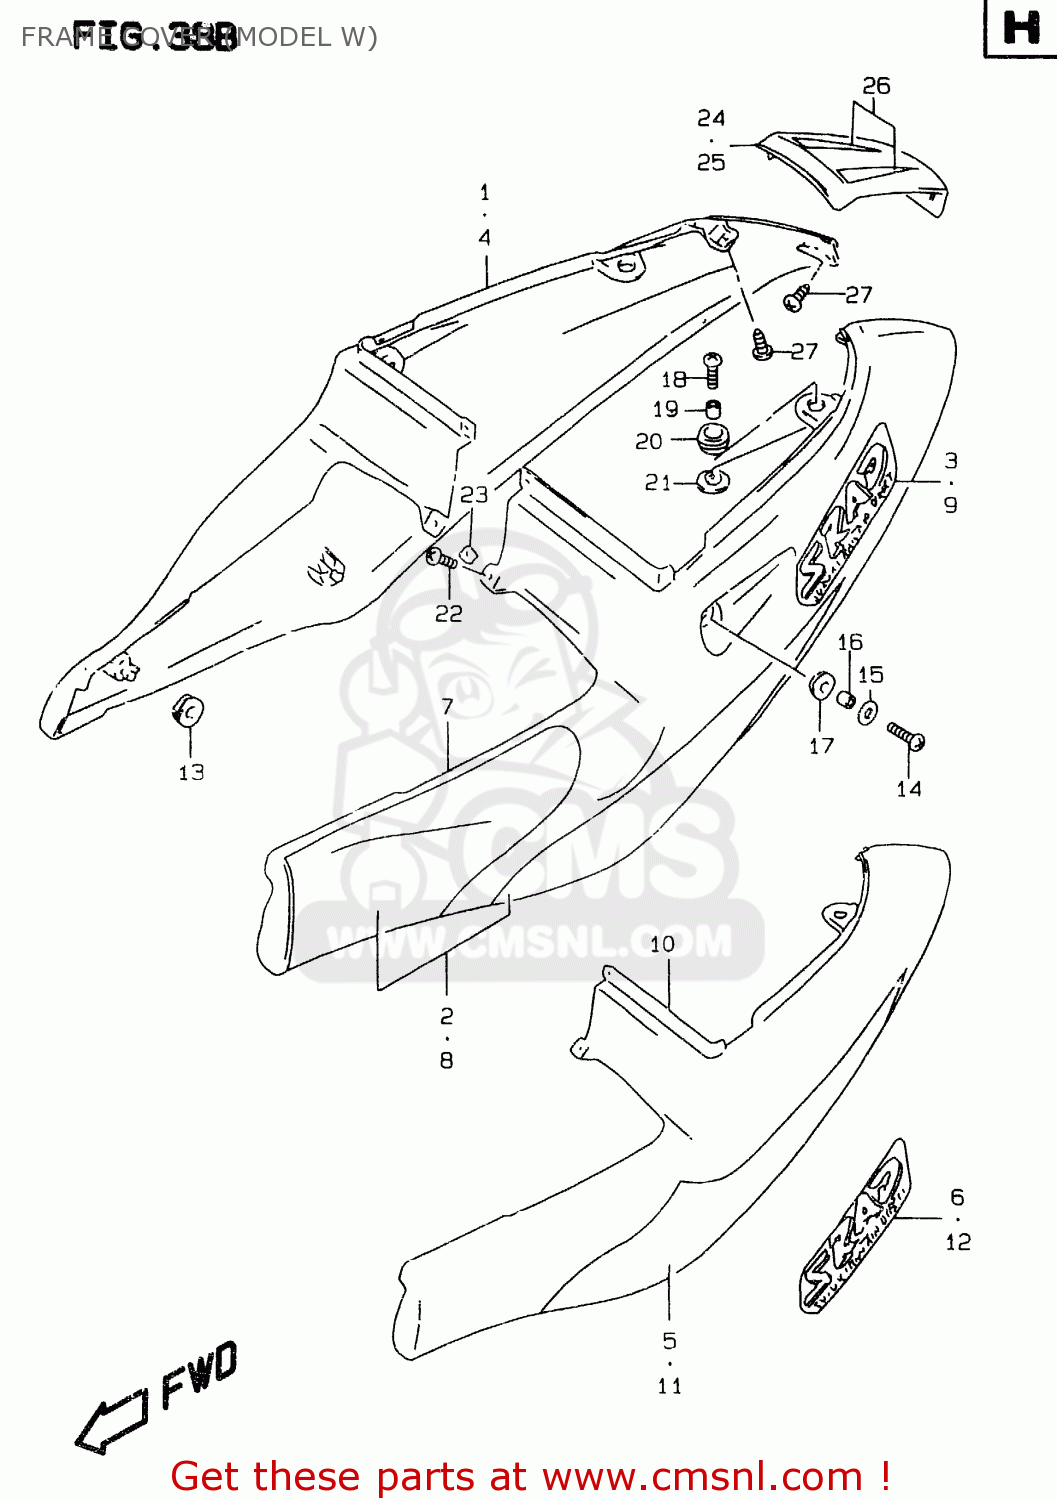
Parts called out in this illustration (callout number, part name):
1	COVER,FRAME,R(BRACK)
2	TAPE SET,FRAME COVER,R
3	EMBLEM,FRAME COVER
4	COVER,FRAME,R(WHITE)
5	TAPE,FRAME COVER,R(BLUE)
6	EMBLEM,FRAME COVER
7	COVER,FRAME,L(BRACK)
8	TAPE SET,FRAME COVER,L
9	EMBLEM,FRAME COVER
10	COVER,FRAME,L(WHITE)
11	TAPE,FRAME COVER,L(BLUE)
12	EMBLEM,FRAME COVER
13	CUSHION
14	SCREW(6X20)
15	WASHER(6.5X22X1.6)
16	SPACER(6.5X9X6.7)
17	CUSHION
18	SCREW(6X25)
19	SPACER(6.5X10X9.4)
20	CUSHION,TAIL COVER UPR
21	CUSHION,FRAME COVER LWR
22	SCREW
23	NUT
24	COVER,FRAME CTR
25	COVER,FRAME CTR
26	TAPE SET,FRAME COVER CTR
27	SCREW
